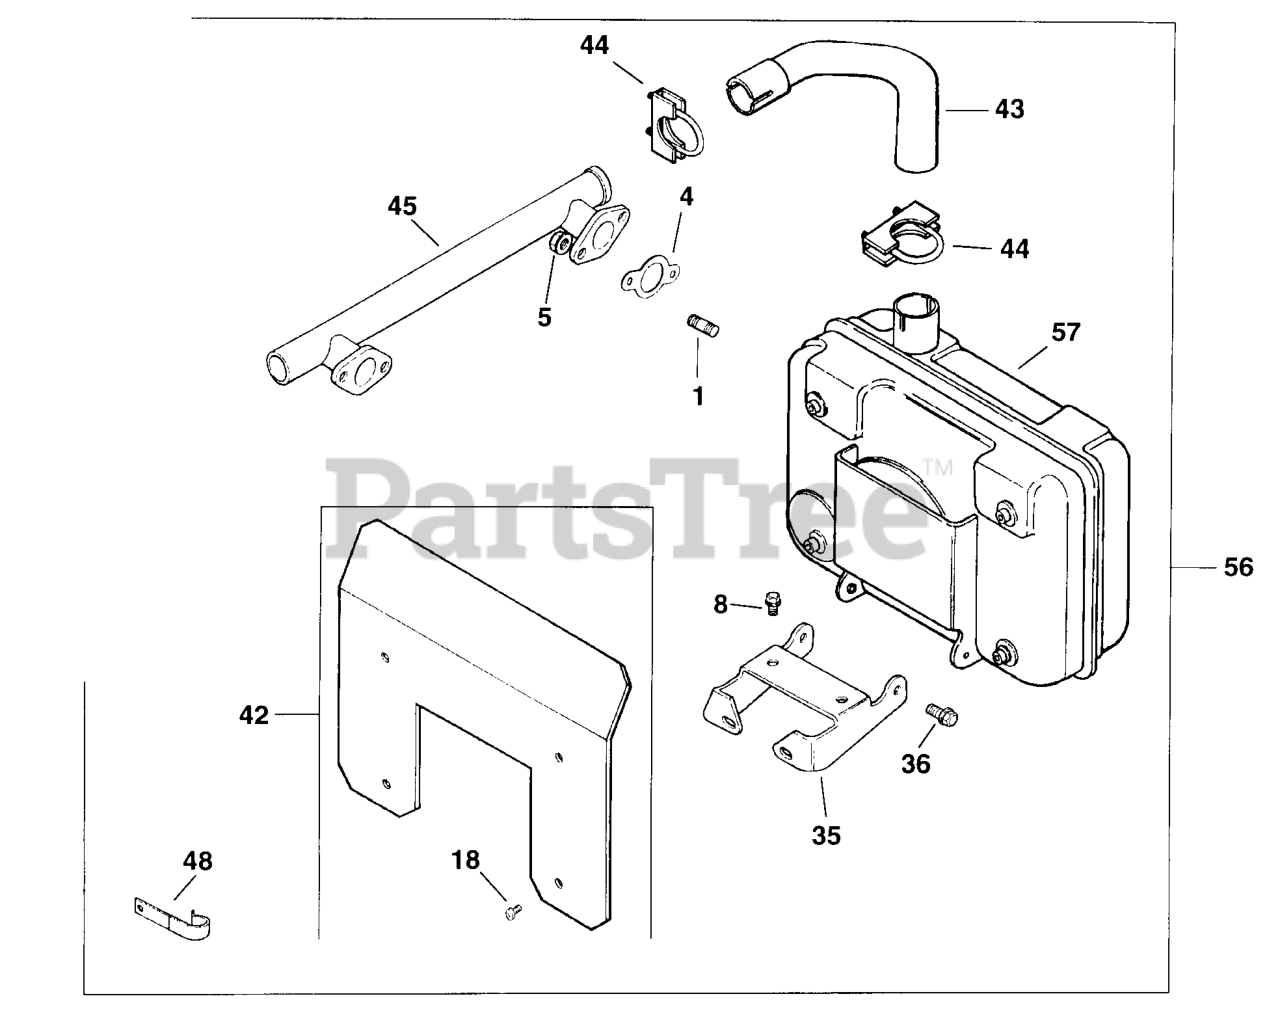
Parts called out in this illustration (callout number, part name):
1	STUD - USE M-829033
5	NUT - USE M-841080
8	Screw, hex. flange M8x1.25x20
18	SCREW - USE M-555010
35	BRACKET, MUFFLER
36	SCREW - USE M-645016
42	KIT, HEAT SHIELD
43	PIPE, EXHAUST
44	CLAMP, MUFFLER
45	MANIFOLD, EXHAUST
48	CLIP, CABLE - USE 24 154 10-S
56	KIT,MUFF-ST SIDE 15.25"x10"x7.5"
57	MUFFLER, STARTER SIDE USE 24 068 152-S
